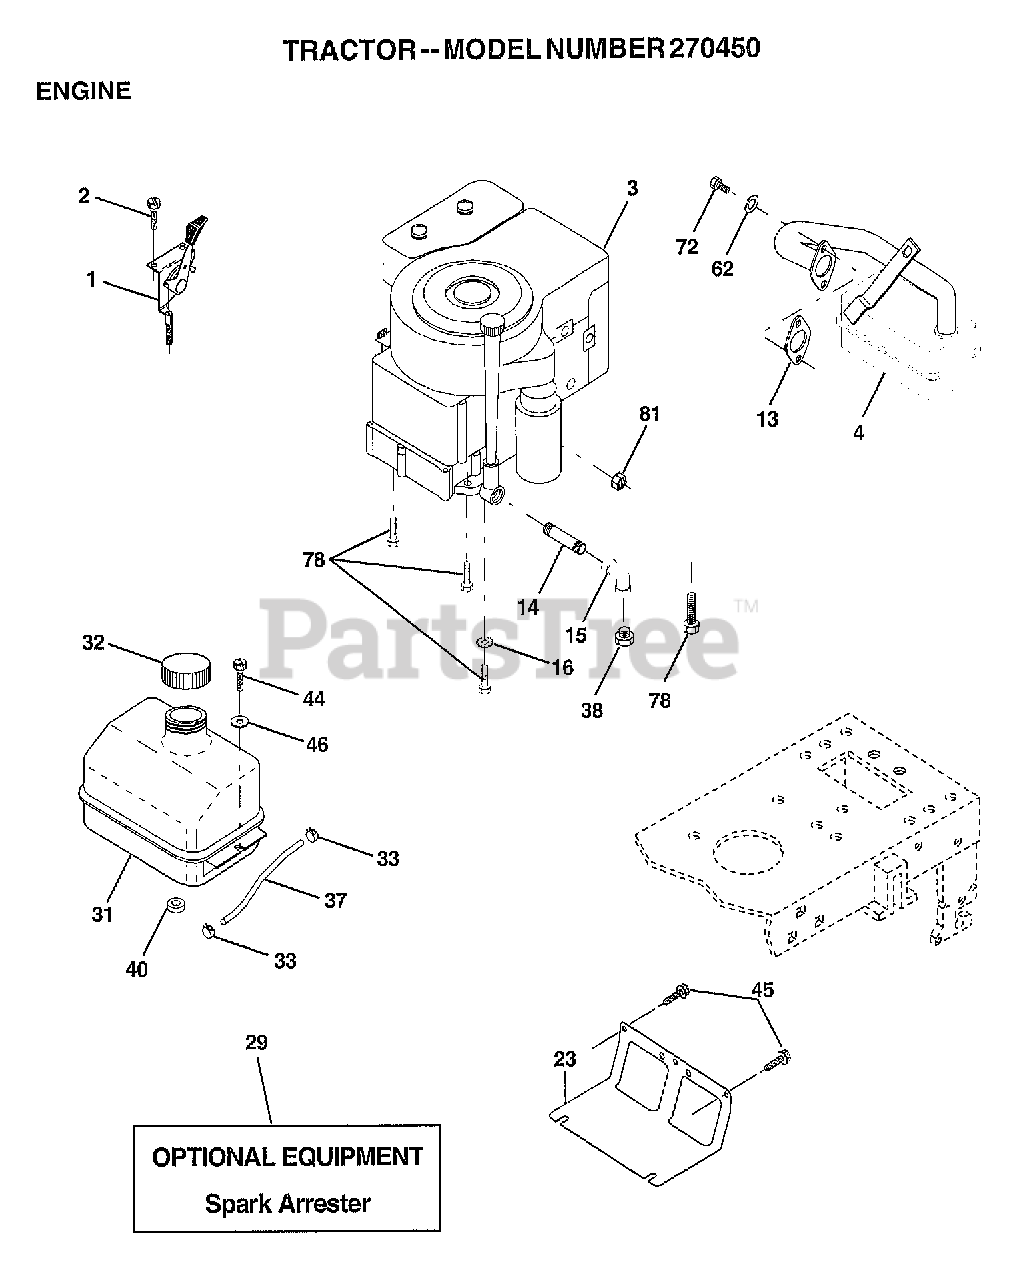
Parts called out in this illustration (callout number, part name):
1	CONTROL THROTTLE
2	SCREW LT
4	MUFFLER
14	PIPE NIPPLE
15	ELBOW
16	LOCKWASHER
23	SHIELD BROWNING
31	TANK.FUEL.LT.
32	CAP ASM FUEL
33	HOSE CLAMP
37	LINE FUEL
44	SCREW HEX CRT
45	SCREW
46	WASHER
62	LOCKWASHER
72	SCREW LT
78	SCREW
81	NUT
